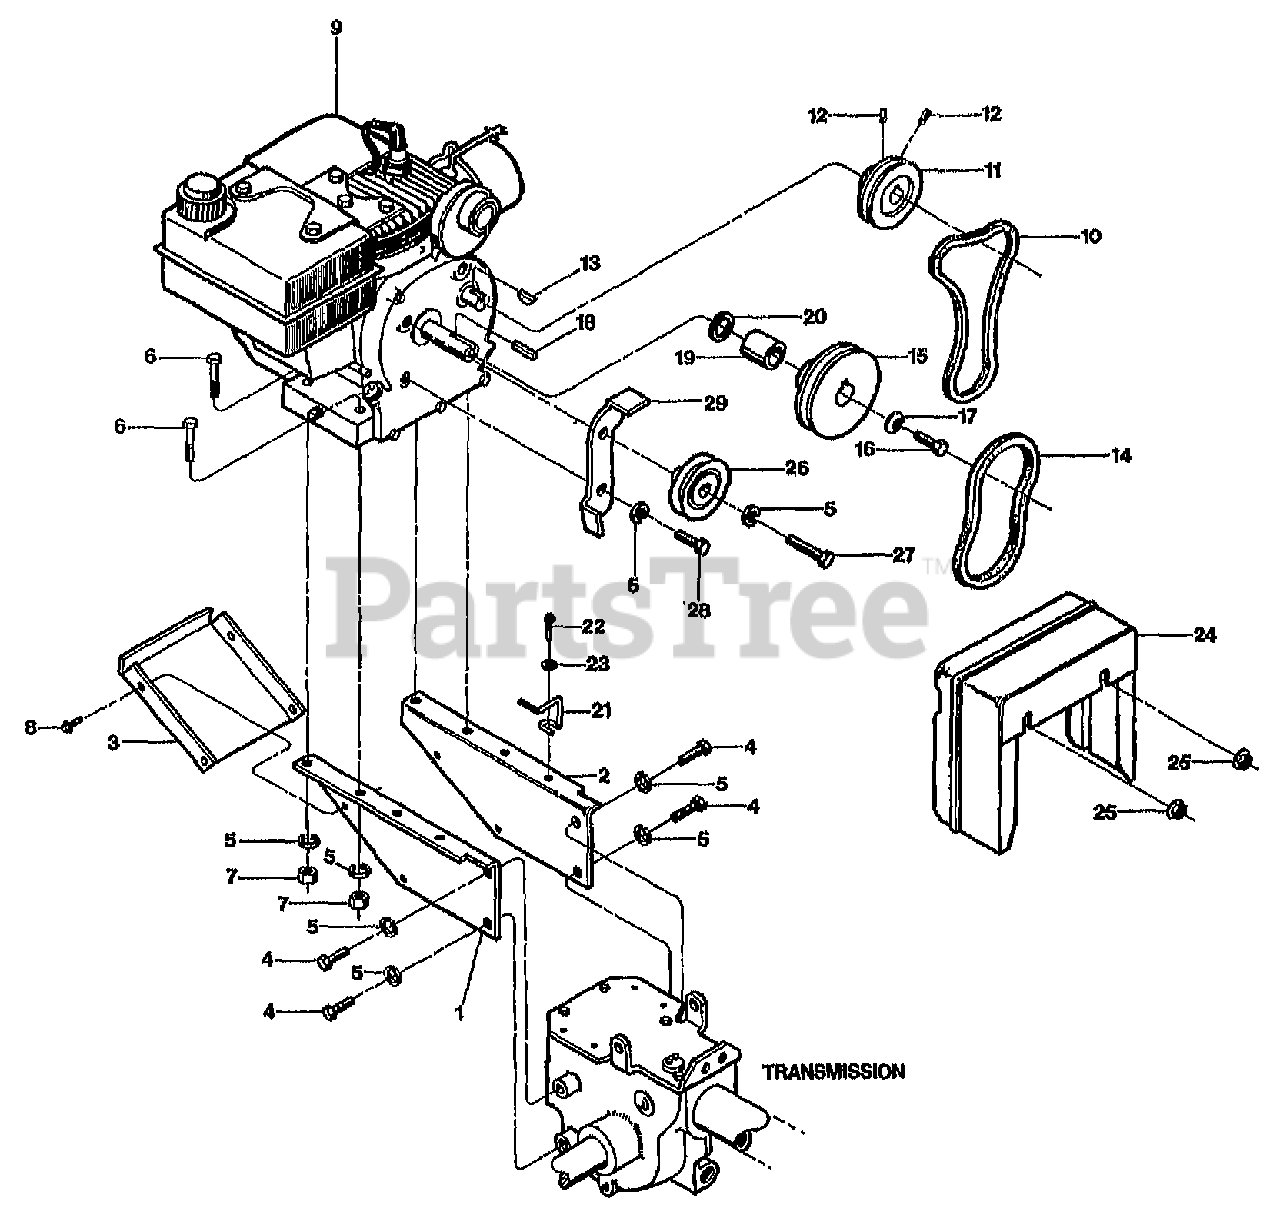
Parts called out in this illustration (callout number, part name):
1	BRKT-ENG LT P4
2	BRKT-ENG RT PNT
3	PAN-ENG BRKT PNT
4	SCR-HHC 5/16-18X.75 GR 5 (Brackets to Transmission)
5	WASHER-LK .312 ZP
6	SCR-HH 5/16-18X1.5 G5 ZP
7	NUT-HEX 5/16-18 ZP
8	SCR-HH SEMS 10-32 X .5 ZP (Sems w/ permanent washer.)
9	Tecumseh, Model H35, Type 45593S
9	Tecumseh, Model H35, Type 45606S
10	BELT-V (Reverse; see V-Belt Set #11018)
11	PULLEY-REVERSE MACH (Engine driven, 1 groove, single belt.)
12	SCR-SS 1/4-20 X .25 (Secures reverse engine pulley.)
13	KEY-WOODRUFF #5 (Reverse pulley to reverse PTO shaft)
14	BELT-V GROOVE FWD SMFRAME (See V-Belt Set #11018)
15	PULLEY-ENGINE MACH (Engine driven, 1 groove single belt)
16	SCR-HH 3/8-24X1.0 G5 ZP (Attaches forward pulley)
17	WASHER-.994X.413X.145 (disc spring; concave surface faces forward pulley.)
18	KEY-.188 SQX1.0 (Forward pulley to forward PTO shaft)
19	SPACER-.755X.937X1.375 (on forward PTO shaft between shim and forward pulley.)
20	SHIM-1.0X.7656X.031 (On forward PTO shaft between Engine and spacer.)
21	GUIDE-BELT FWD
22	SCR-HWH 1/4-20 X .75 STH
23	WASHER-FLAT 1/4 SAE
24	COVER - Shields belts and pulleys
25	NUT-HFLK 5/16-18 ZP
26	IDLER-V-GROOVE (Reverse Idler (Internal bushing type)
27	BOLT-HH 5/16-24 X 1.5 ZP
28	SCR-HH 5/16-24X.50
29	GUIDE-BELT REV PNT
